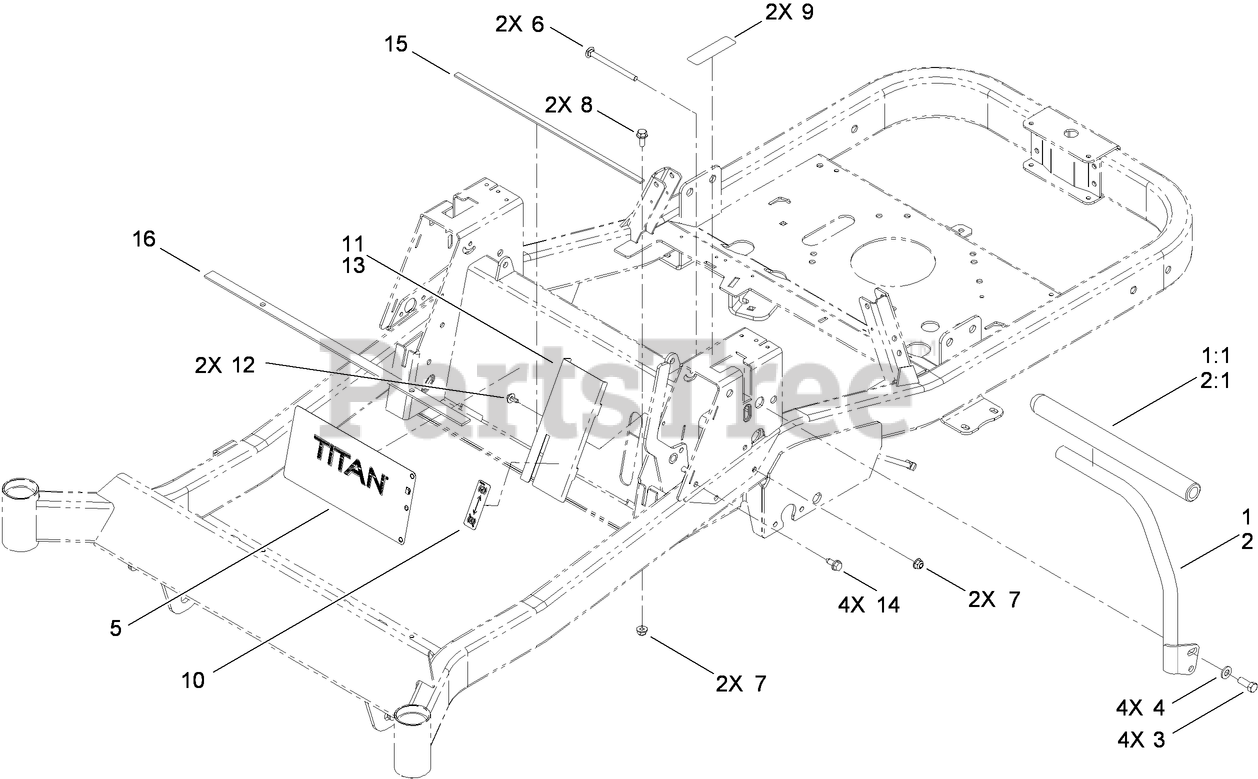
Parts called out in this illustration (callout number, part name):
1	LH CONTROL HANDLE ASM
3	SCREW-HH
4	WASHER-FLAT
5	DECAL-TITAN
6	SCREW-CARR
7	NUT-HF, NI
8	SCREW-HHF
9	DECAL-CONTROL, MOTION
10	DECAL-BRAKE, PARKING
11	COVER-CONTROL, LH
12	SCREW-HHFTF
14	SCREW-HWHTF
15	STRIP-VIBRATION, ANTI
16	STRIP-VIBRATION, ANTI
